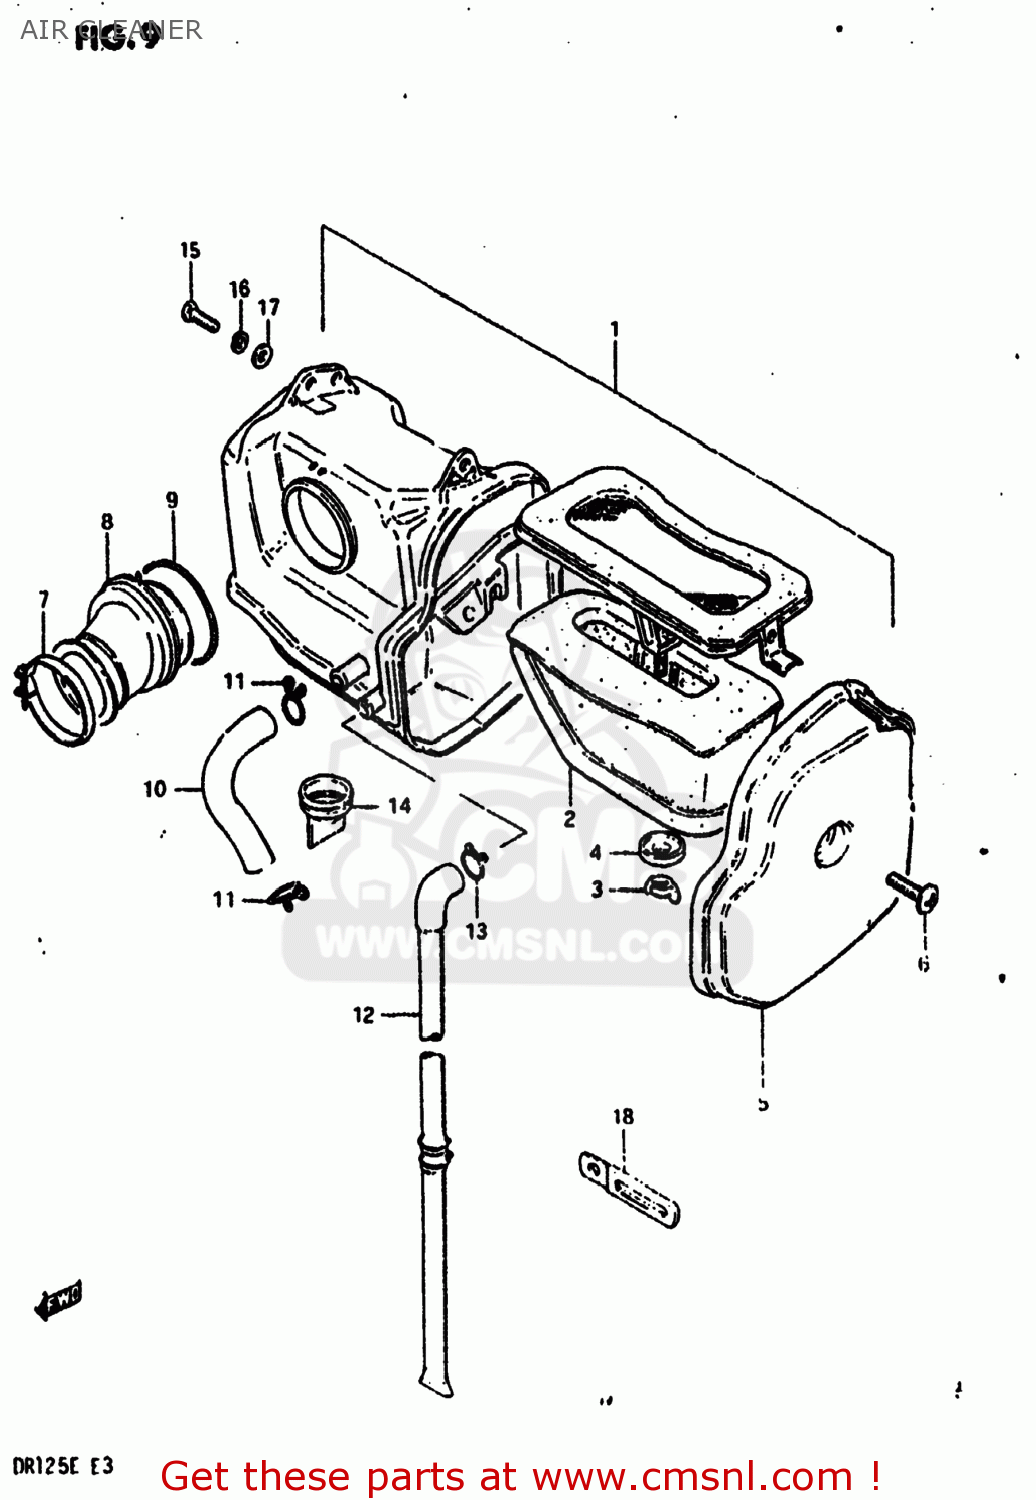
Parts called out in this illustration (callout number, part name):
1	CLEANER ASSEMBLY,AIR
2	ELEMENT,AIR CLEANER
3	NUT
4	WASHER
5	CAP
6	SCREW, COVER SIDE
7	CLAMP
8	CLAMP,CLEANER SIDE
9	TUBE,OUTLET
10	TUBE,AIR CLEANER BREATER
11	CLAMP
12	HOSE,AIR CLEANER DRAIN
13	CLAMP
14	DRAIN TUBE
15	BOLT, UPPER
16	LOCK WASHER
17	WASHER
18	CLAMP
